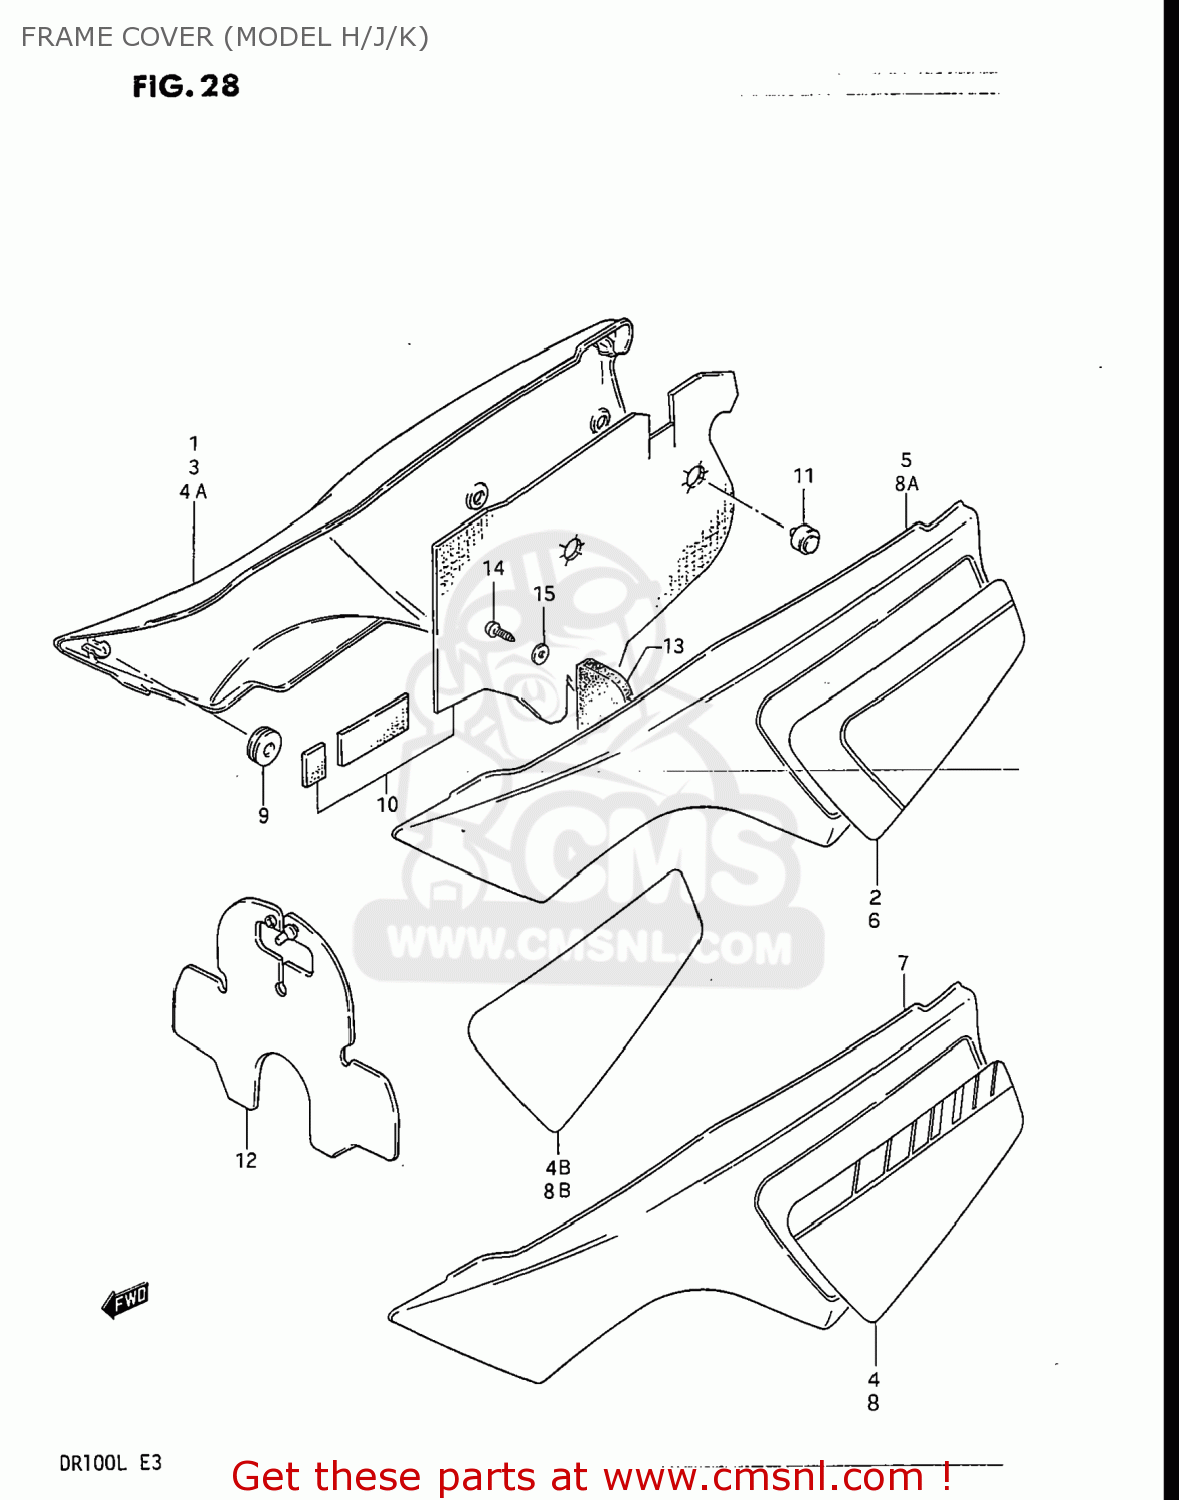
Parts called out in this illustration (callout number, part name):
1	COVER,FRAME,RIGHT
2	TAPE SET,FRAME COVER,RIGHT
3	COVER,FRAME,RIGHT
4	TAPE,FRAME COVER,RIGHT
4A	COVER,FRAME,RIGHT
4B	TAPE,FRAME COVER,RIGHT (BLUE)
5	COVER,FRAME,LEFT
6	TAPE SET,FRAME COVER,LEFT
7	COVER,FRAME,LEFT
8	TAPE,FRAME COVER,LEFT
8A	COVER,FRAME,LEFT
8B	TAPE,FRAME COVER,LEFT (BLUE)
9	CUSHION
10	HEAT SHIELD SET,FRAME
11	CUSHION
12	MUD FLAP,FRONT
13	MUD GUARD,AIR CLEANER
14	SCREW
15	WASHER 4MM
